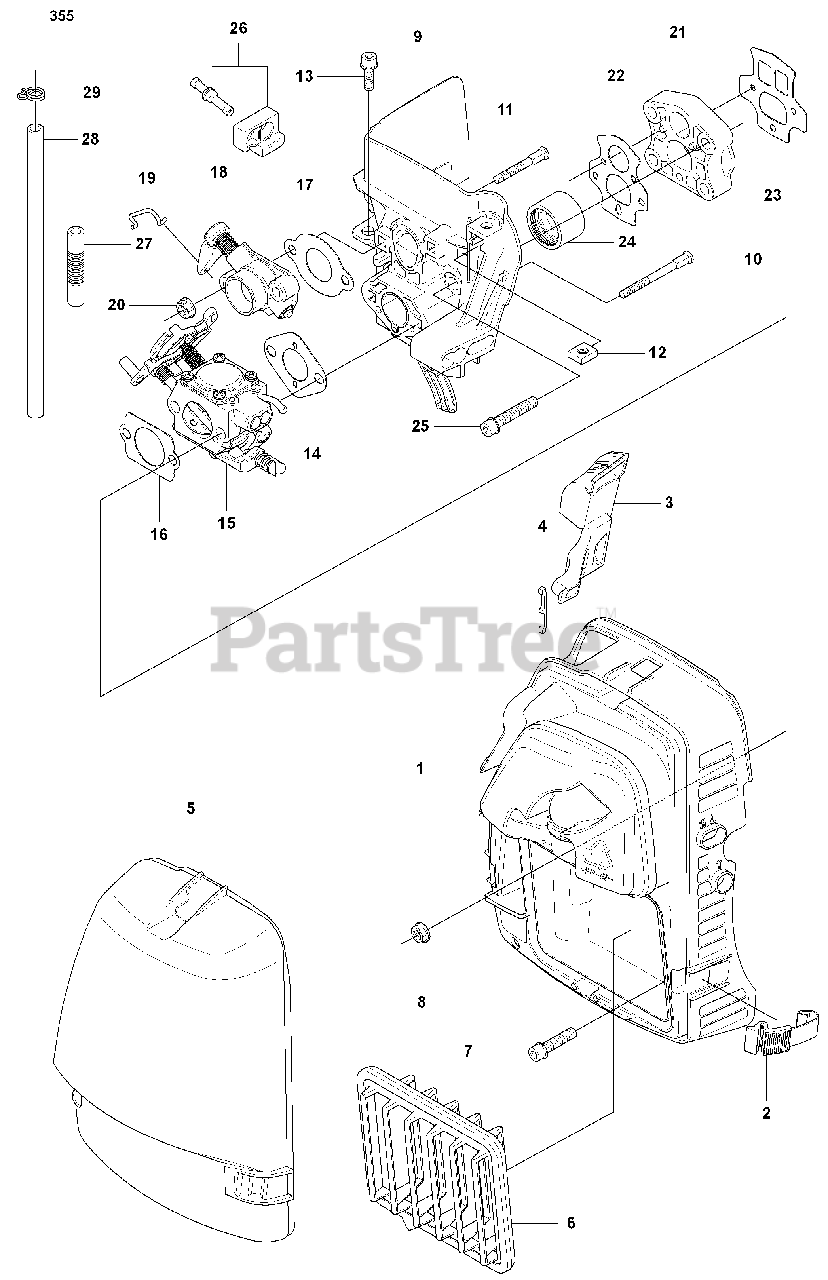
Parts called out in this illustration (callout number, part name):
1	FILTER HOLDER
3	CHOKE CONTROL
5	FILTER COVER
6	FILTER
9	INSULATION WALL
14	%GASKET
15	CARBURETOR WT-814A
18	VALVE HOUSING
24	INLET PIPE
25	SCREW IHSCFM
27	SUCTION HOSE
28	RP FUEL HOSE
29	HOSE CLAMP
